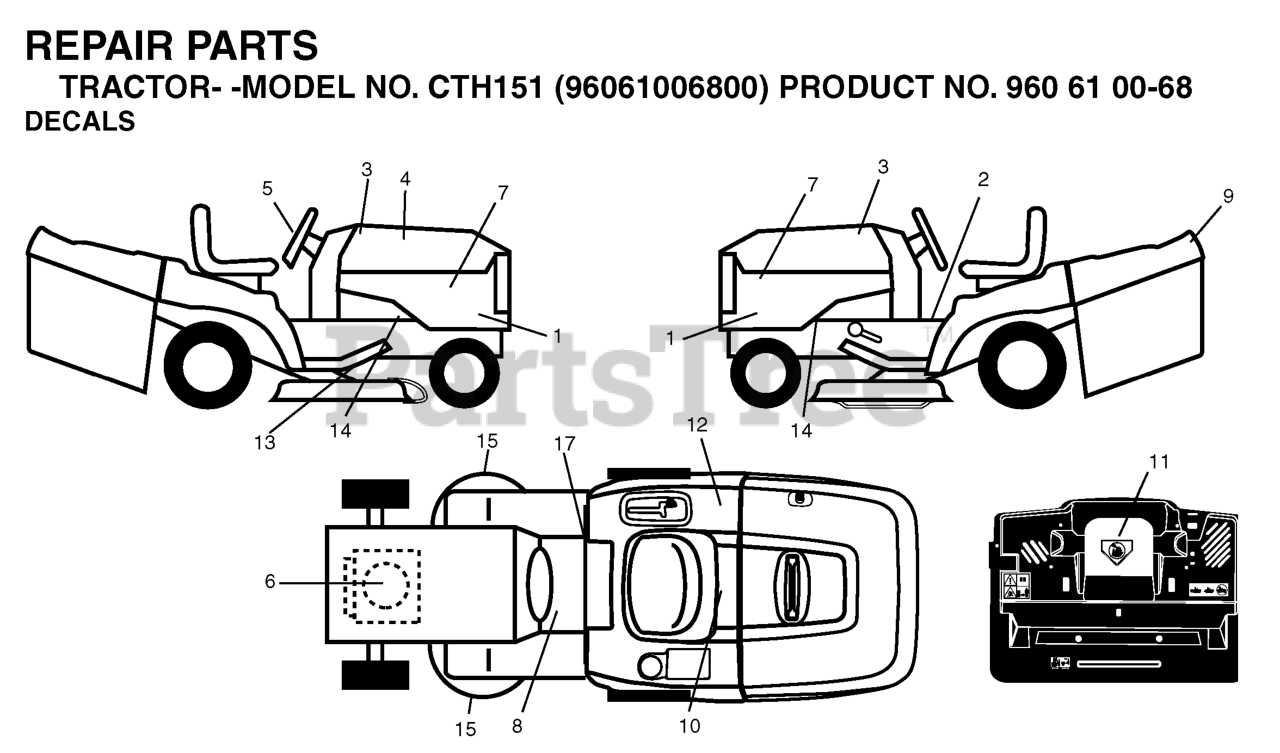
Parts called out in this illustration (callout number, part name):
2	LABEL
5	DECAL.STEERING.HUSQ.BLUE
6	DECAL
7	DECAL.HOOD.HUSQVARNA.INTERNATI
8	DECAL
10	DECAL BTRY SYMBOLS
11	DECAL.INTERNATIONL.CUTFINGER
12	Decal, Fender 100 DB/CE
17	DECAL PARK BRAKE
